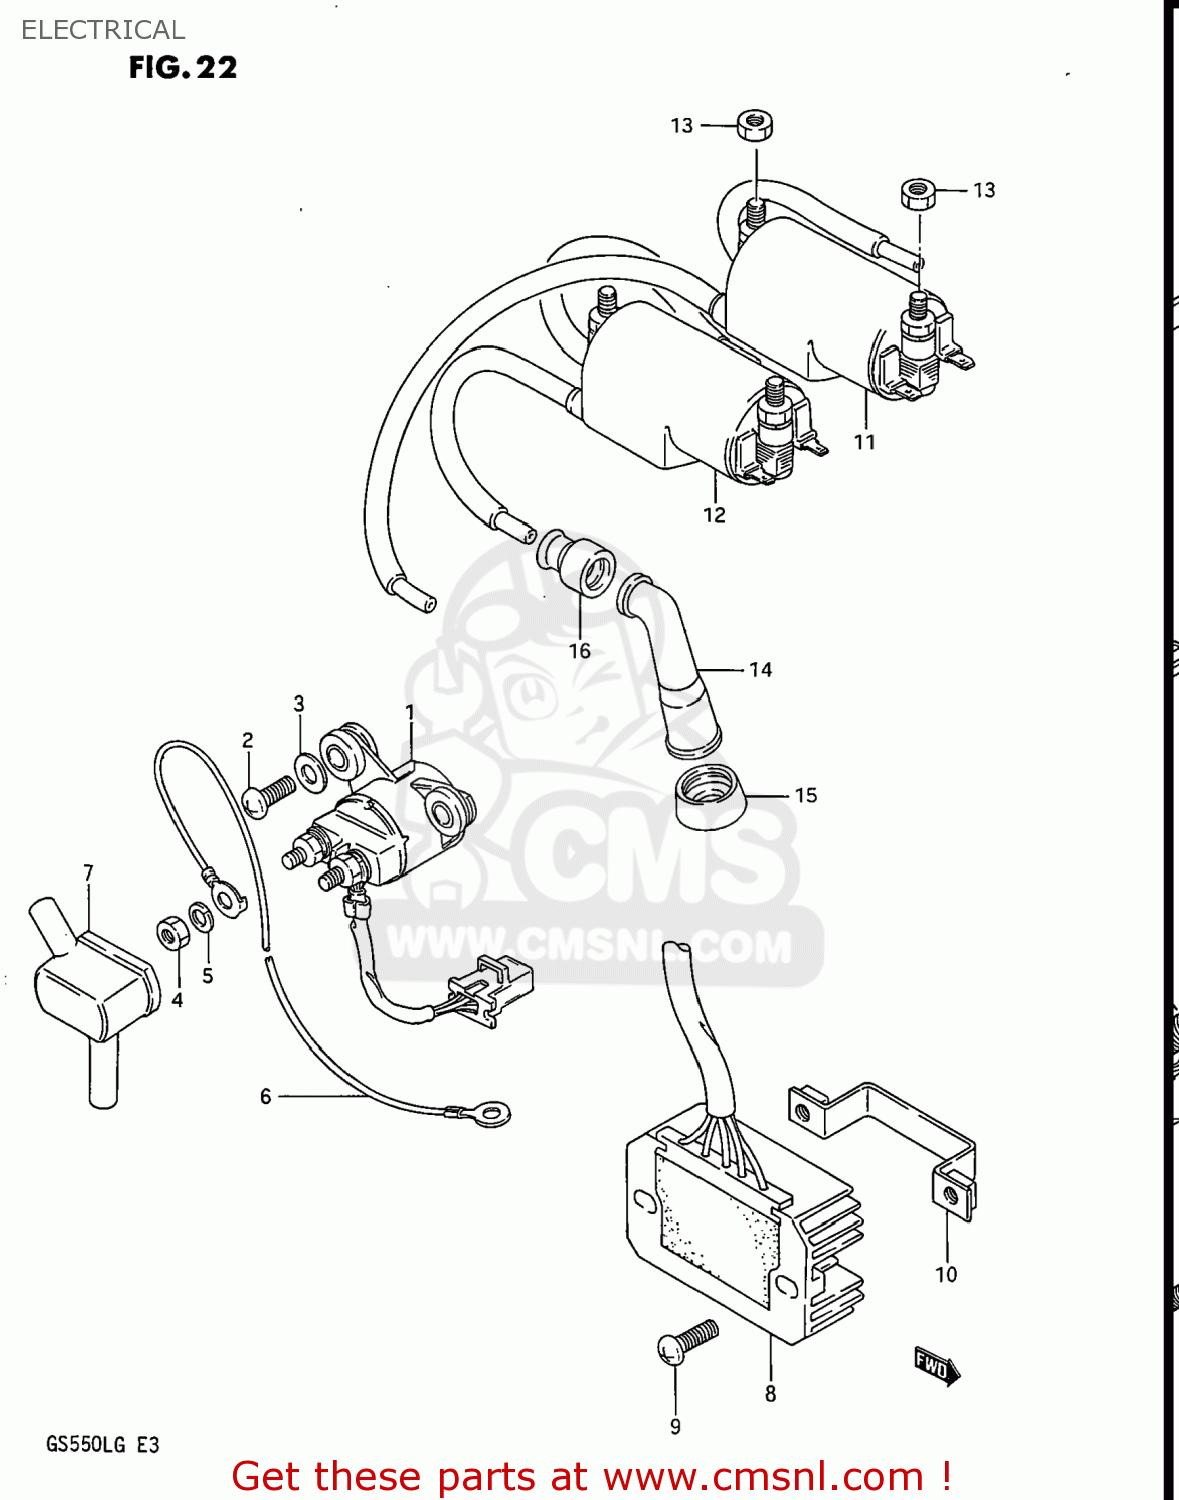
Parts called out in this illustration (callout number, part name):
1	RELAY ASSY,STARTING MOTOR
2	SCREW
3	WASHER
4	NUT
5	WASHER,LOCK
6	WIRE,STARTER MOTOR LEAD
7	CAP,STARTER RELAY
8	RECTIFIER ASSEMBLY
9	SCREW
10	BRACKET,RECTIFIER
11	COIL ASSEMBLY,IGNITION
12	COIL ASSEMBLY,IGNITION
13	NUT 6MM
14	CAP ASSY,SPARK PLUG
15	SEAL,SPARK PLUG CAP
16	SEAL,SPARK PLU
